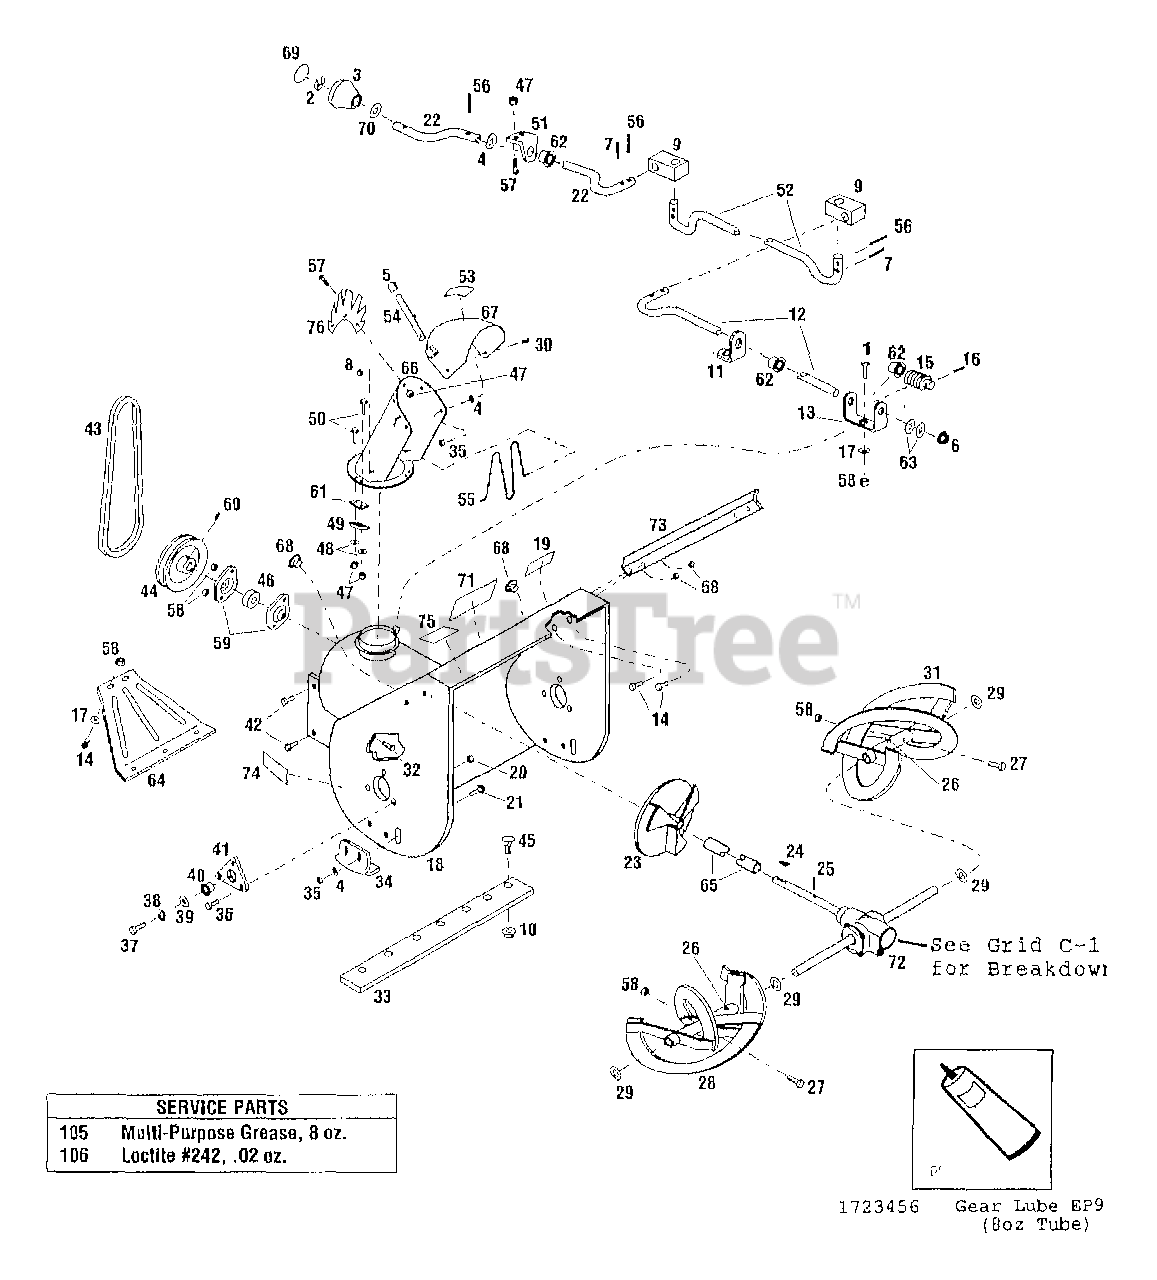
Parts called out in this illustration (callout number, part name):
1	SCR-HFLK 5/16-18X.75 ZP
2	RETAINER-3/8
4	WASHER-FLAT 3/8 SAE
5	GRIP-VACUCUT
6	NUT-HF/LK 3/8-16
7	PIN-ROLL 1/8 X 3/4
8	NUT-PUSH 3/16
9	BLOCK-SWIVEL NYLON
10	NUT-HFLK 5/16-18 ZP
11	SUPPORT-CRANK
12	SHAFT-CHUTE CONTROL
13	SUPPORT-GEAR
14	SCR-HHC 5/16-18X.75 GR 5 ZP
15	GEAR-WORM LH
16	PIN-DRIVE .09X.75
17	WASHER-FLAT 5/16 SAE
18	HOUSING-24" W/DECAL
18	HOUSING-26" W/DECAL
19	DECAL-WARNING
20	NUT-HT LK 1/4-20
21	BOLT-3/8-16 X 3/4
22	CRANK-CHUTE CONTROL
24	KEY-WOODRUFF .188X.75
24	KEY-HI PRO .187X.75
25	PIN-ROLL 1/4 X 1-1/4
26	FITTING-GREASE
27	SHEARBOLT AND NUT
28	AUGER-RH
28	ASSM-AUGER RH
29	WASHER-SPEC
30	SCR-HH 3/8-16X.75 G5 ZP
31	AUGER-LH
31	ASSM-AUGER LH
32	SCR-CARR 5/16-18X.75 G2 ZP
33	SCRAPER-BLADE
33	BLADE-SCRAPER
34	RUNNER-SKIP
35	NUT-LOCK 3/8-16
36	SCR-HH 1/4-20X.625 G5 ZP
37	SCR-HH 1/2-13X.75 G5 ZP
38	WASHER-LK .5
39	WASHER-1/2 FLAT
40	BUSHING-FLANGE
41	SUPPORT-BEARING
42	SCR-HH 3/8-16X.50
43	BELT-V 38"
43	BELT-V (SET OF 2)
44	SHEAVE-AUGER
44	PULLEY-AUGER
45	SCR-CARR 5/16-18X.62 G2 ZP
46	BEARING-BALL
47	NUT-H/LK M10-24 NYLOCK
47	NUT-HEX TOP LK 10-24 NYLK
48	WASHER-.505X.22X.05
49	CLIP-HOLD DOWN
50	SCR-HW M10-24X.88 EXTTOOTH
51	SUPT-CHUTE CONTROL
52	ROD-CHUTE CRANK
53	DECAL-WARNING
54	LEVER-ADJUSTING
55	GUARD-CHUTE
56	PIN-COTTER .093X.625
57	SCR-TR HD 10-24X.375
58	NUT-TOP/LK 5/16-18 ZP
59	BEARING-FLANGE
60	SCR-SQ HD SET 5/16X3/4
62	BUSHING-NYLON
63	BUSHING-NYLON
64	SUPPORT-HOUSING
65	SLEEVE-IMPELLER SHAFT
66	ASSM-DISCHARGE CHUTE
67	CAP-DEFLECTOR W/DECAL
69	IY-KNOB SPUN SILVER
70	WASHER-FLAT .375DIA
71	DECAL-LOGO
72	ASSM-GEAR CASE
73	KIT-SLICER DRIFT (2)
74	DECAL-HOUSING SIDE
75	DECAL-AMERICAN LEGEND-LRG
76	DEFLECTOR-CHUTE
105	GREASE-8 OZ MULTI PURPOSE
106	LOCTITE-242 (.5 ML TUBE)
1723456	LUBE-EP90 8OZ
